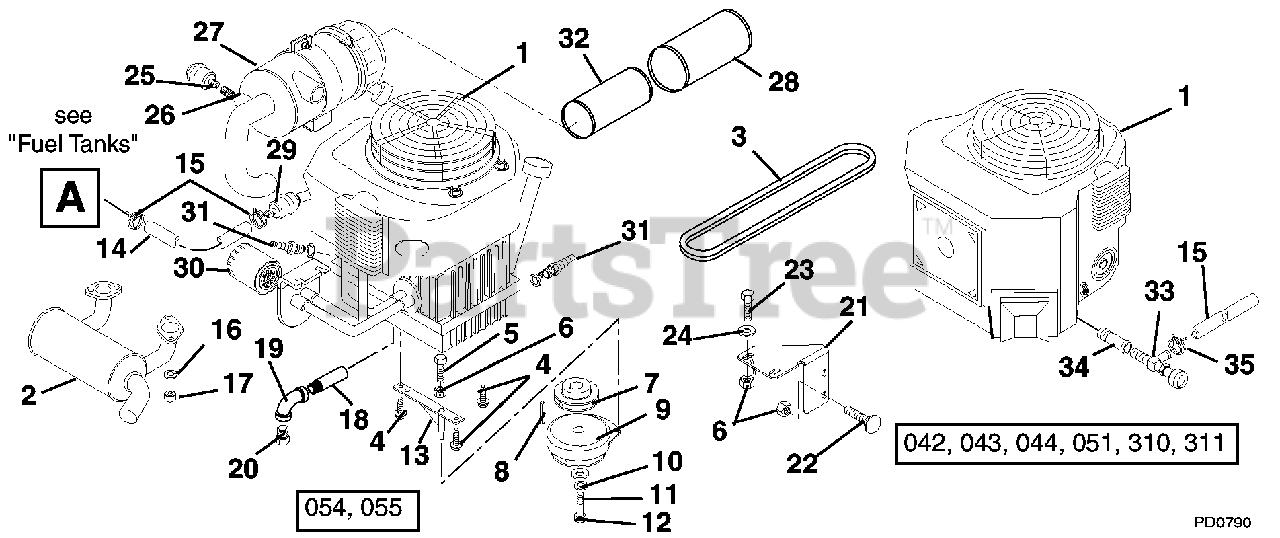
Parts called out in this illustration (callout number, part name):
1	Engine, Kohler, 25HP (054, 055)
1	Engine, Kawasaki 19HP (042, 310)
1	Engine, Kawasaki 21HP (043, 311)
1	Engine, Kawasaki 23HP (044, 051)
2	Muffler, Kohler (054, 055)
2	Muffler, Kawasaki (042, 043, 044, 051, 310, 311)
3	V-Belt HA 52 x .535 G48667
4	Screw, Tapping Hex Washer Head .38-16 x 1.00
5	Bolt, Hex .31-18 x 1.50 Grade 5
6	Nut, Locking Top Flange .31-18 (054, 055)
6	Nut, Locking Top Flange .31-18 (042, 043, 044, 051, 310, 311)
7	Pulley-V 4.00 x 1.125 with Key 1.42 Height
8	Key, Square .25 x .625 x .25 SAE 8630 OR SAE 1035
9	Clutch, Electric
10	Washer, Flat Steel .515 x 1.625 x .250
11	Washer, Locking .44 x .109
12	Bolt, Hex .44-20 x 2.50 Grade 5
13	Weldment, Clutch Anchor
14	Gas Line, Bulk .25 ID
15	Hose, Clamp
16	Washer, Lock .31 x .078 Regular
17	Nut, Hex M8-1.25
18	Nipple (054, 055)
19	Elbow .375-18 (054, 055)
20	Pipe Plug (054, 055)
21	Bracket, Oil Filter Mounting-Kohler (054, 055)
22	Bolt, Round Head Square Neck .31-18 x .62 (054, 055)
23	Bolt, Hex .31-18 x 1.00 Grade 5 (054, 055)
24	Washer, Flat Steel .38 x .875 x .083 (054, 055)
25	Filter Minder (054, 055)
26	Nipple, .125 NPT (054, 055)
27	Assembly, Air Cleaner
28	Filter, Outer Element
29	Fuel Filter, Kohler (054, 055)
29	Fuel Filter, Kawasaki (042, 043, 044, 051, 310, 311)
30	Oil Filter, Kohler (054, 055)
30	Oil Filter, Kawasaki (042, 043, 044, 051, 310, 311)
31	Spark Plug, Kohler (054, 055)
31	Spark Plug, Kawasaki (042, 043, 044, 051, 310, 311)
32	Filter, Inner Element
33	Cock, Oil Drain (042, 043, 044, 310, 311)
34	Adapter, Oil Drain (042, 043, 044, 310, 311)
35	Gas Line, Bulk .25" ID (042, 043, 044, 310, 311)
